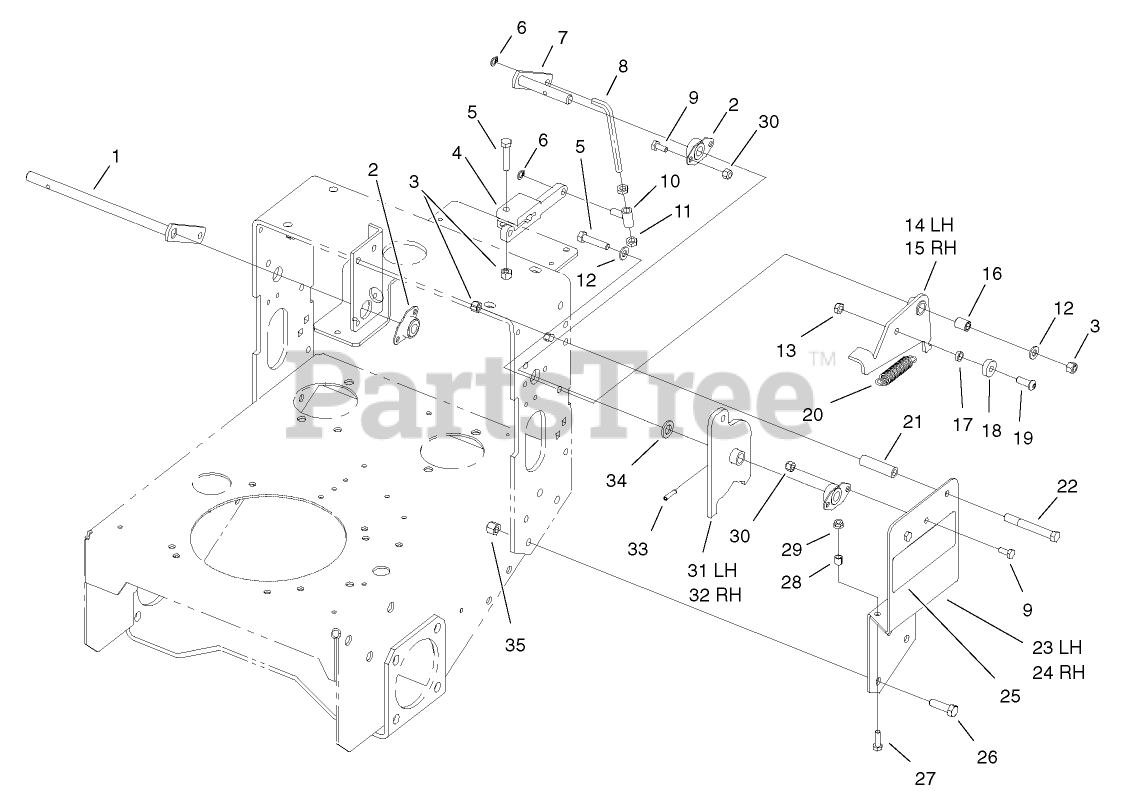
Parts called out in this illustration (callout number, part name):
1	LEVER-PIVOT, RH
2	SIDE FLANGE BEARING ASM
3	NUT-LOCK, NI
4	ARM-PUMP
5	SCREW-HH
6	RING-GRIP
7	LEVER-PIVOT, LH
8	ROD-LINK
9	SCREW-HH
10	SLEEVE
11	NUT-JAM
12	WASHER-PLAIN
13	NUT-LOCK, NI
14	ARM-DETENT, LH
16	BUSHING-ARM, DETENT
17	SPACER-BEARING
18	BEARING-BALL
19	SCREW-HSBH
20	SPRING-DETENT
21	SPRING-EXTENSION
22	SCREW-HH
23	BRACKET-PIVOT, LEFT
25	DECAL-HYDRO
26	SCREW-HH
27	SCREW-HH
28	SPACER-TUBULAR
29	NUT-LOCK, HHF
30	NUT-LOCK, NI
31	ARM-PIVOT, LH
33	PIN-ROLL, SLOTTED
34	WASHER-THRUST
35	NUT-LOCK, NI
